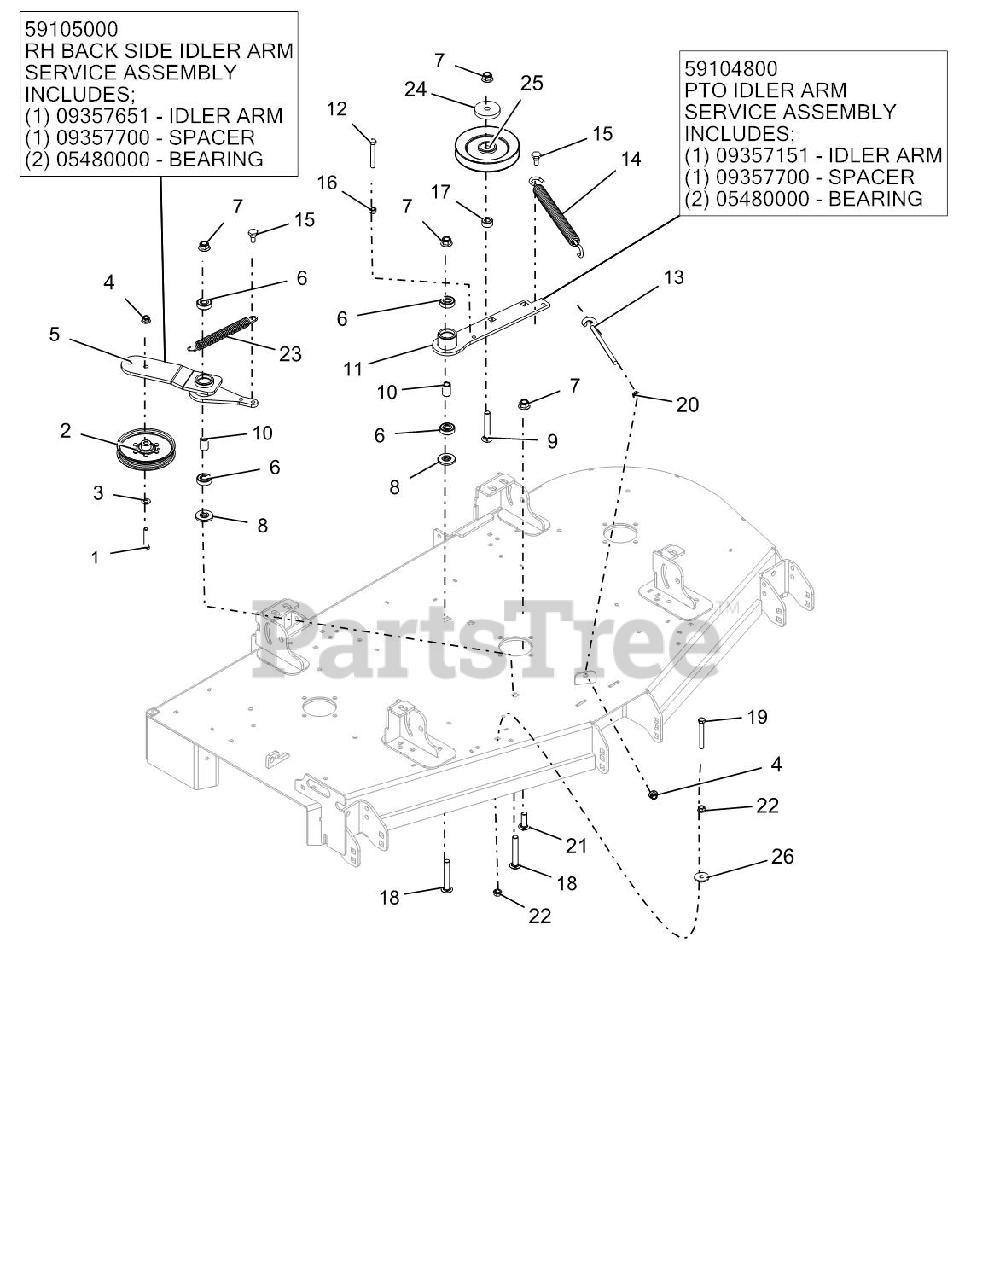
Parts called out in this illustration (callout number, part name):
1	BLT-HEX .38-16X2.00 GR5 YWZC
2	PULLEY, FLAT IDLER .500 X .375 W/BRG
3	WSHR-FL-STL.406X.812X.065 YWZ
4	NUT-LK-NYL-FLG .38-16 YWZC
5	RH BACK SIDE IDLER ARM SERVICE ASSEMBLY
5	IDLER ARM
5	SPACER
5	BEARING
5	WLDMT, DECK RH IDLER ARM
6	BRG-BALL .500X1.375X.44
7	NUT-LK-NYL-FLG .50-13 YWZC
8	SPACER, IDLER ARM
9	BLT-RDHDSQNK .50-13X3.00 G5 Y
10	SPACER, .510 X .750 X 1.148
11	PTO IDLER ARM SERVICE ASSEMBLY
11	IDLER ARM
11	SPACER
11	BEARING
11	WLDMT, DECK PTO IDLER ARM-BLACK
12	BLT-HEX .38-16X2.75 GR5 YWZC
13	BOLT, .38-16X6.00 .62 DIA EYE
14	SPRG, EXTENSION - SWIVEL
15	BLT, SHLDR EP .38-16X.30 HEX YZ
16	NUT-HEX .38-16 YWZC
17	BSHG, SPCR .502 X .997.50 PM
18	BLT-RDHDSQSHNK .50-13X3.25 YWZC
19	BLT-HEX .38-16X3.00 GR5 YWZC
20	NUT, JAM .375-16 YWZC
21	BLT-RDHDSQSHNK .50-13X1.50 YWZC
22	@NUT-SPNLK-FLG .375-16 YWZC
23	SPRG, EXTENSION .120X.845X6.55 WLD
24	CAP, IDLER BEARING SEALING
25	SHEAVE, .50" ID X 6.00" OD V-IDLER
26	WASHER-FLAT-STL, .406 X 1.375 X .135
